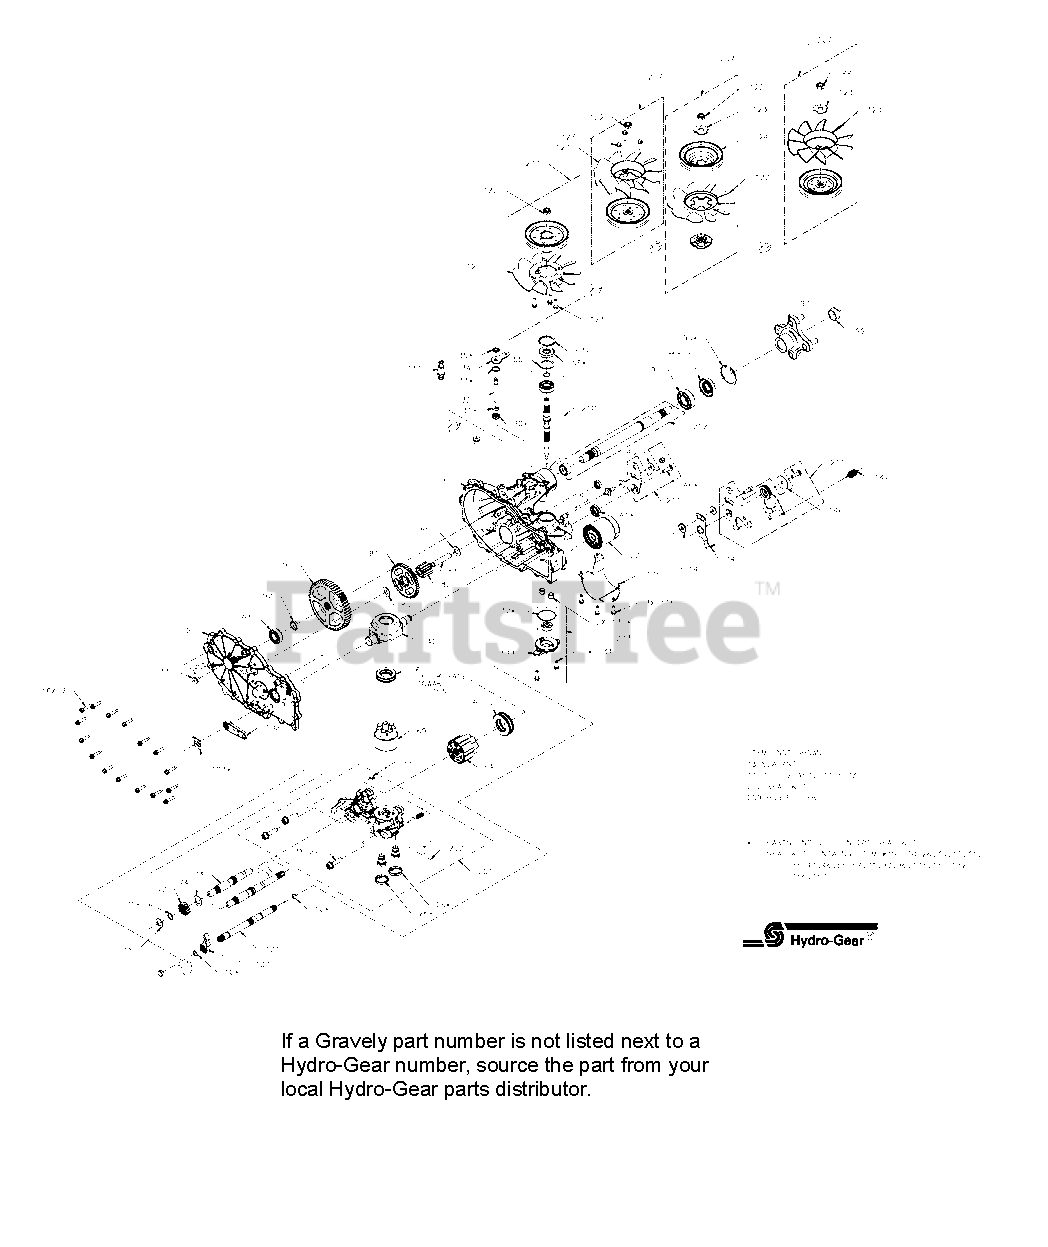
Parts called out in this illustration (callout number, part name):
1	KIT, HOUSING, MAIN, RH, CHRG, CNTL
2	KIT, COVER, SIDE, RH
7	HFHCS 1/4-20 x 1.125"
10	O-RING - 111 .103 x .424
11	PLUG 9/16-18 (METAL)
13	SEALANT
14	OIL, 20W50
22	PLATE, BYPASS
23	FILTER, OIL
26	SEAL, PLUG 1.250 x .250
27	HFHCS 3/8-16 x 1.5 (PATCH)
30	SEAL, LIP .375 x .75 x .25
31	RING, RET .375 EXTRNL
32	ROD, BYPASS
33	RING, RET .750 INTRNL
34	ARM, BYPASS
35	RING, RTNG .375 EXT
40	TRUNNION, SWASHPLATE
41	SEAL, LIP 12 x 32 x 7
45	WASHER .34 x .88 x .06
46	TWHCS 5/16-24 x 1.00 (PATCH)
55	WASHER 1.23 x 1.56 x .04
56	SEAL, LIP 17 x 40 x 7
57	RING, RETAINING
60	BEARING, THRUST
64	ASS'Y, CYLINDER BLOCK, 16cc
65	BRG, THRUST BALL 30 x 52 x 13
69	ASS'Y, BLOCK 7 PISTON
70	WASHER .63 x 1.0 x .05
71	RING, RETAINING_.625
72	GEAR, 16T
73	SHAFT, MOTOR
74	WASHER .72 x 1.16 x .04
80	WASHER .5 x 1.0 x .03
81	GEAR, 43T
82	GEAR, 11T
83	JACK SHAFT (PIN)
90	RING, RET 2.06 INT
91	GEAR, 54T
92	SPACER, .75 x 1.32 x .257
93	BEARING, BALL, .75 x 40 x 12
95	BRG, BALL 1.0 x 52 x 15 OPEN 6205M
96	SEAL, LIP 25 x 52 x 10 TC (GRAY)
97	KIT, HUB, 4 BOLT
99	NUT, HEX LOCK 3/4-16
100	PAWL, BRAKE
101	SHAFT, BRAKE
102	HANDLE, ACTUATING
103	CLIP, RETAINING
105	HFHCS 1/4-20 x .75
106	GUARD, FILTER, RH
111	FITTING, STR 9/16-18 SAE .5 BARB
120	FAN 7", 10 BLADE
122	NUT, HEX JAM 1/2-20 W/PATCH
123	HFHCS 1/4-20 x .875
130	TUBE, CONNECTING
131	GEROTOR ASSEMBLY (1.9 cc/rev)
132	O-RING, -137, 0.103 x 2.050
133	COVER, CHARGE PUMP
134	HFHCS 1/4-20 x .75
140	SPACER .320 x 1.005 x .179
141	ARM, NEUTRAL RIGHT
142	SHCS 5/16-24 x 1 PATCH
146	WASHER, .343 x 1.500 x .062
147	SPRING, EXTNSN RTN-34LBS
200	KIT, SEAL
201	KIT, CENTER SECTION, RH, CHRG
202	KIT, CHARGE RELIEF
203	KIT, CHARGE PUMP
207	KIT, FAN & PULLEY
209	UB PULLER, 4 BOLT
210	KIT, INPUT SHAFT
211	KIT, RTN, CW
212	KIT, SHAFT, AXLE
